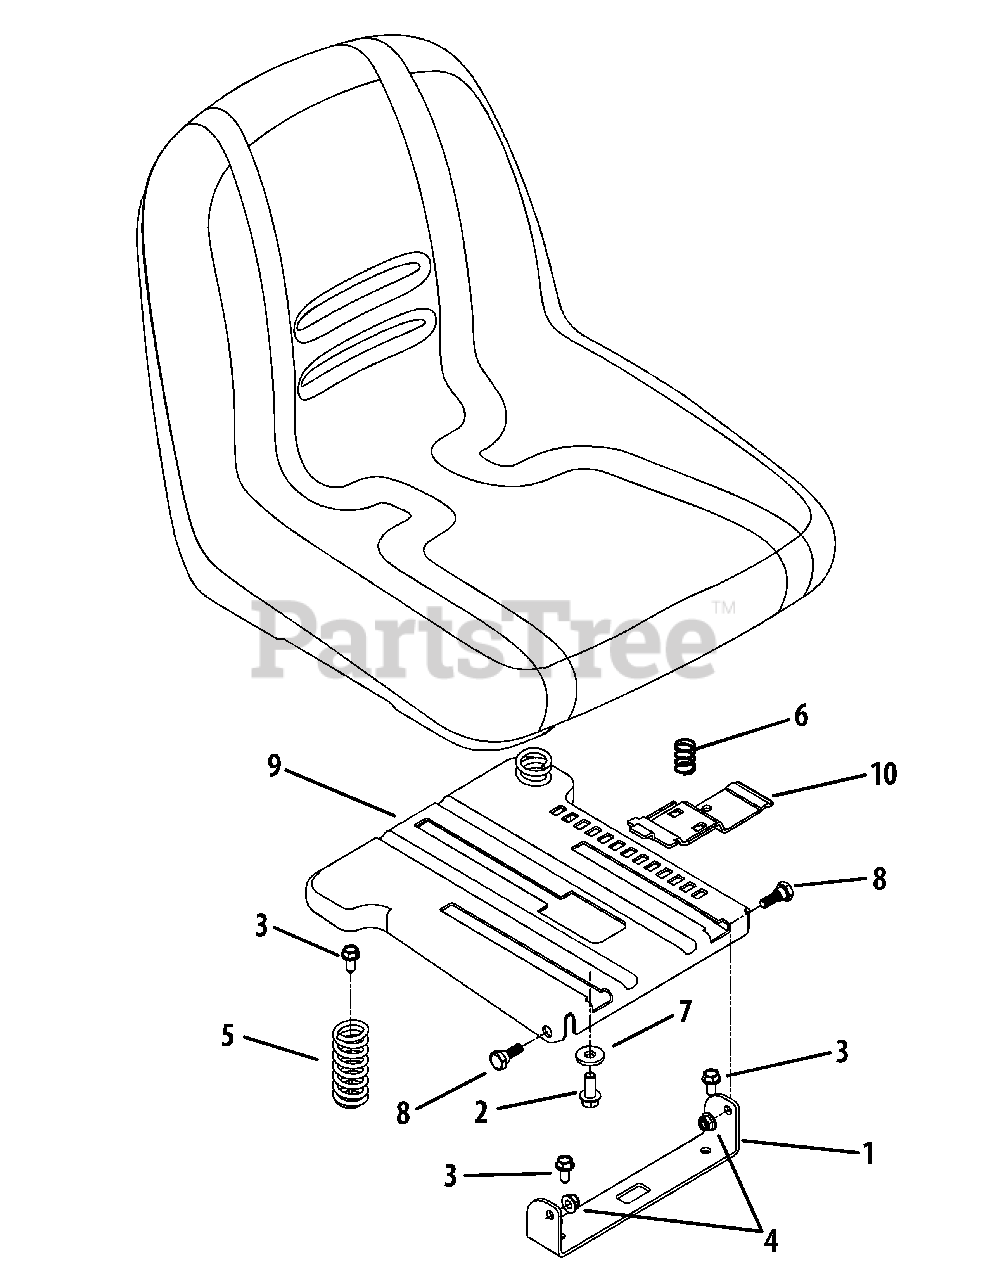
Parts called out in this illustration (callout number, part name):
2	Hex Flange Bolt 3/8-16 x .875
3	Hex Washer Screw 5/16-18 x .75
4	Flange Locknut 5/16-18 Gr. F, Nylon
5	Compression Spring
6	Compression Spring
7	Flat WAsher .385 x 1.0 x .135
8	Shoulder Screw
9	Seat Mount Bracket
10	Seat Adjustment Lever
